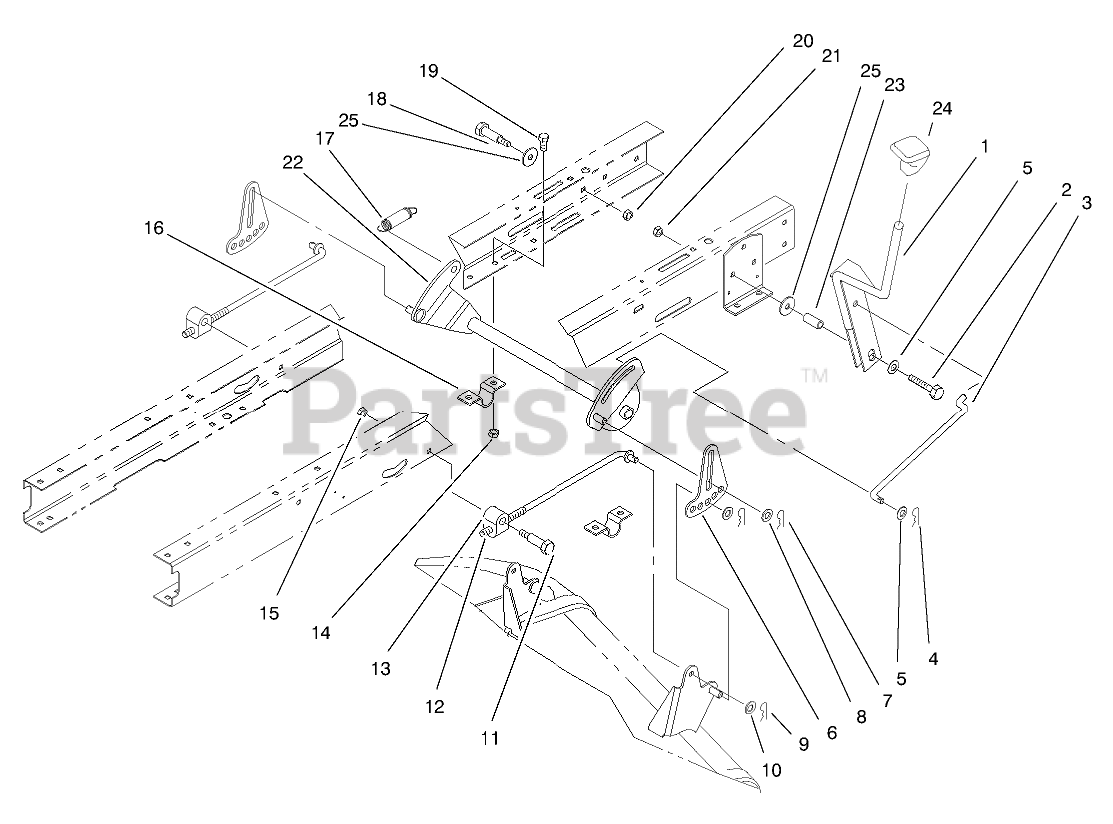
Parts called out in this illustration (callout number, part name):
1	HOC LEVER ASM
2	SCREW-HH
3	LINK-HOC
4	PIN-COTTER
5	WASHER-FLAT
6	LINK-ADJUSTING, HOC
7	PIN-COTTER
8	WASHER-HARDENED
9	PIN-COTTER
10	WASHER-FLAT
11	SCREW-SHOULDER, HH
12	ROD-HANGER, REAR
13	TRUNNION-HOC
14	NUT-LOCK, NI
15	NUT-LOCK, NI
16	CLAMP-PIVOT, HOC
17	SPRING-EXTENSION
18	SCREW-SHOULDER, HH
19	SCREW-HH
20	NUT-LOCK, NI
21	NUT-LOCK, NI
22	PIVOT ASM
23	SPACER
24	KNOB-SHIFT
25	WASHER-PIVOT
